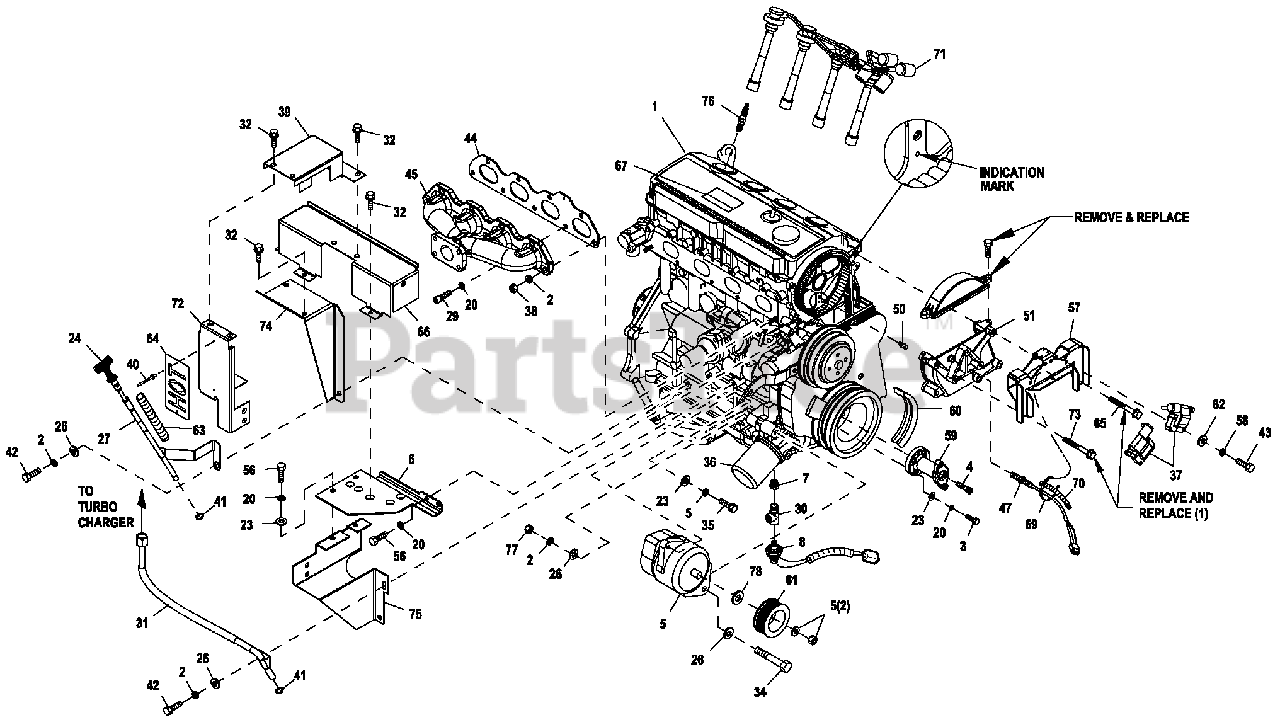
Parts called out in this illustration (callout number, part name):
1	TURBOCHARGER 2.4L 36KW 1800RPM
2	GASKET EXH MAN/TURBO
3	OIL SUPPLY 3LHA(38")
4	ADAPTER 1/2NPTXM16-1.5
5	ADAPTER 1/4NPT X M12-1.5
6	ADAPTER 90D JIC37 1/4NPT X 1/2
7	WASHER FLAT .34IDX.75OD
8	WASHER LOCK M8 SS
9	SCREW HHC M8-1.25 X 35 SS FTH
10	ADAPTOR 1/2 NPT X 37JIC 3/4-16
11	ADAPTER 90D JIC37 1/8NPT X 1/2
12	SCREW THF M6-1 X 16 N WA Z/JS
13	CLAMPSTL/VNL .5X .4 0 6 Z
14	BRKT-EXH MANF 2.4L G2 36KW
15	SCREW HHTT M6-1.0X 1 2 ZINC
16	TUBE TURBO OIL RETURN G2 36KW
17	O-RING SIZE 9.0MM X 2.0MM NITR
